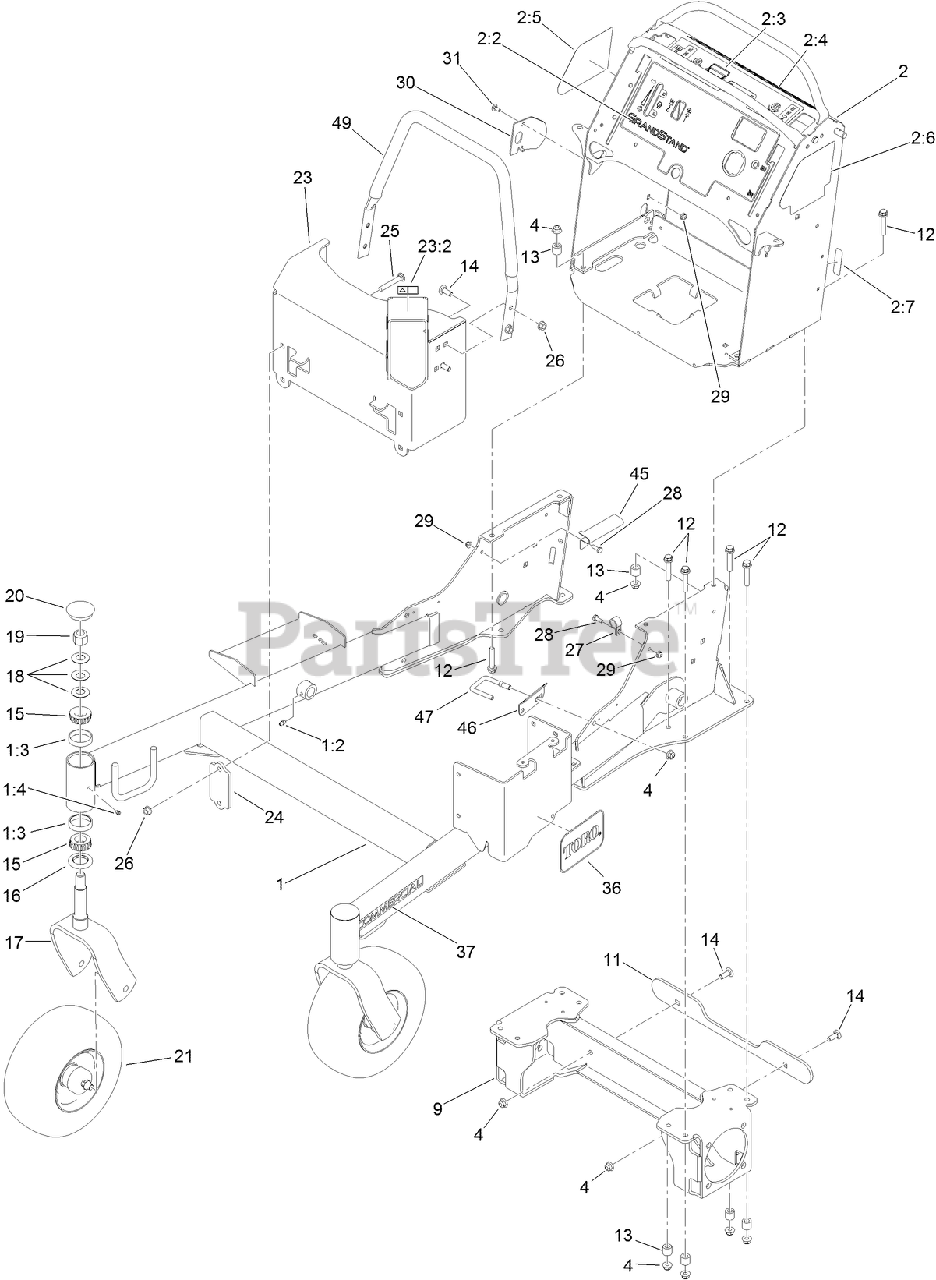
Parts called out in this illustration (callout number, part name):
1	FRONT FRAME ASM
1:2	FITTING-GREASE
1:3	CUP-BEARING
2	CONTROL TOWER ASM
2:2	DECAL-PANEL, CONTROL
2:3	DECAL-OPC
2:4	DECAL-WARNING
2:5	DECAL-HOC
2:6	DECAL-SERVICE/SPARK ARREST
2:7	DECAL-FUSE
4	NUT-HF, NI
9	FRAME-MOTOR
11	PLATE-SPACER, BUMPER
12	SCREW-HHF
13	SPACER
14	SCREW-CARR
15	BEARING-ROLLER, TAPERED
16	SEAL-GREASE
17	FORK-CASTER
18	WASHER-BELLVILLE
19	NUT-LOCK, NI
20	CAP-GREASE
21	WHEEL/TIRE AND BEARING ASM
23	MUFFLER GUARD ASM
23:2	DECAL-WARNING
24	BRACKET-MOUNTING, GUARD
25	SCREW-CARR
26	NUT-HF
27	CLAMP-CABLE
28	SCREW-HH
29	NUT-HF
30	PLATE-STRIKER
31	SCREW-CARR
36	DECAL
37	DECAL-COMMERCIAL
45	BRACKET-HOSE, FUEL (DOUBLE)
46	GUARD-HOSE
47	GUIDE-HOSE
49	TUBE-GUARD
